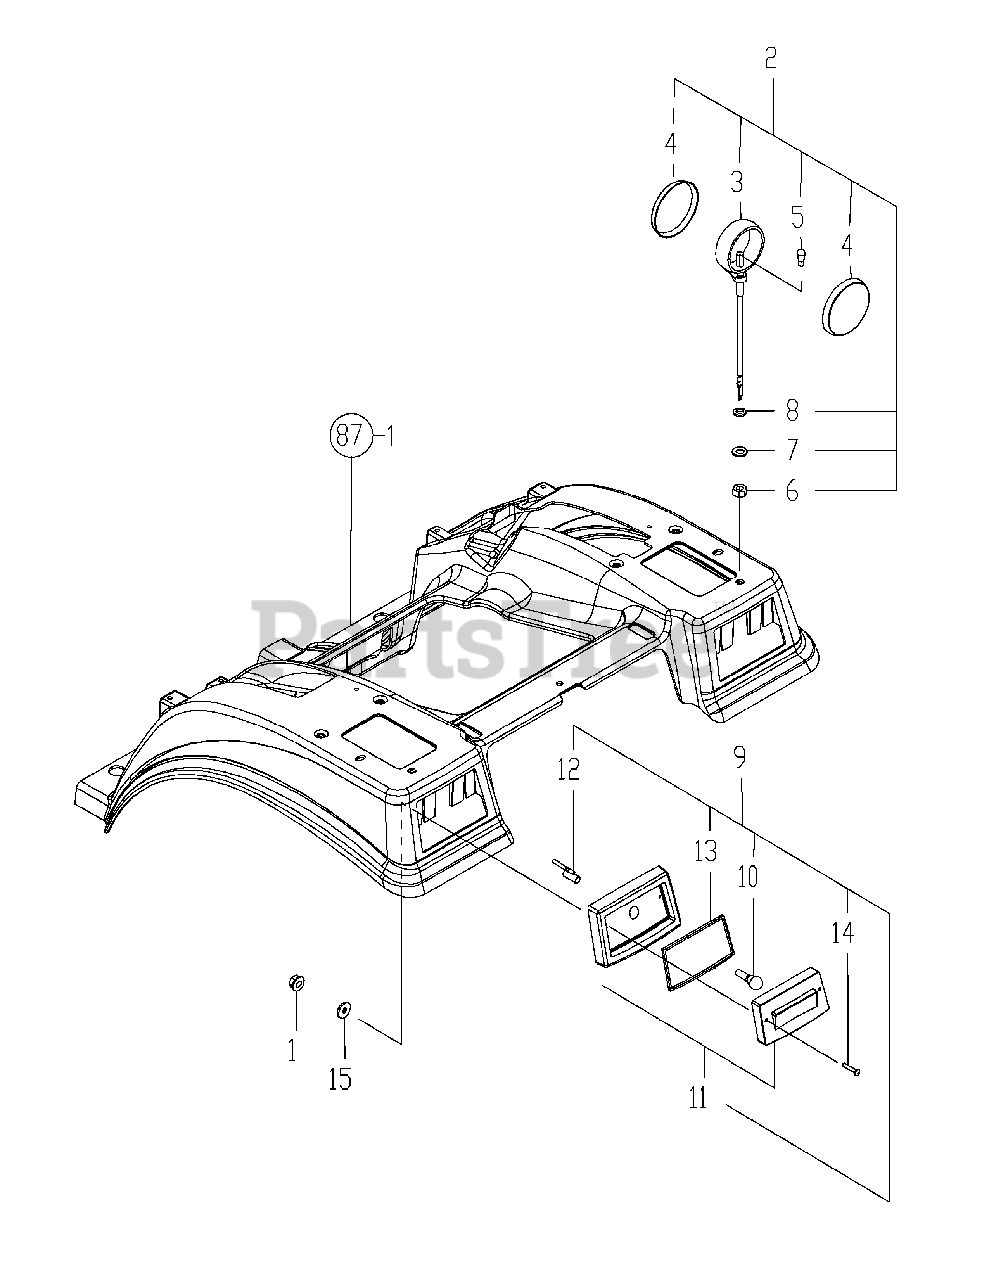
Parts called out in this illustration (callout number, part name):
2	LAMP ASSY,FLASHER
3	HOUSING
6	NUT, 1/2
10	BULB 12V-21/5W
12	HOUSING SEMI ASSY
